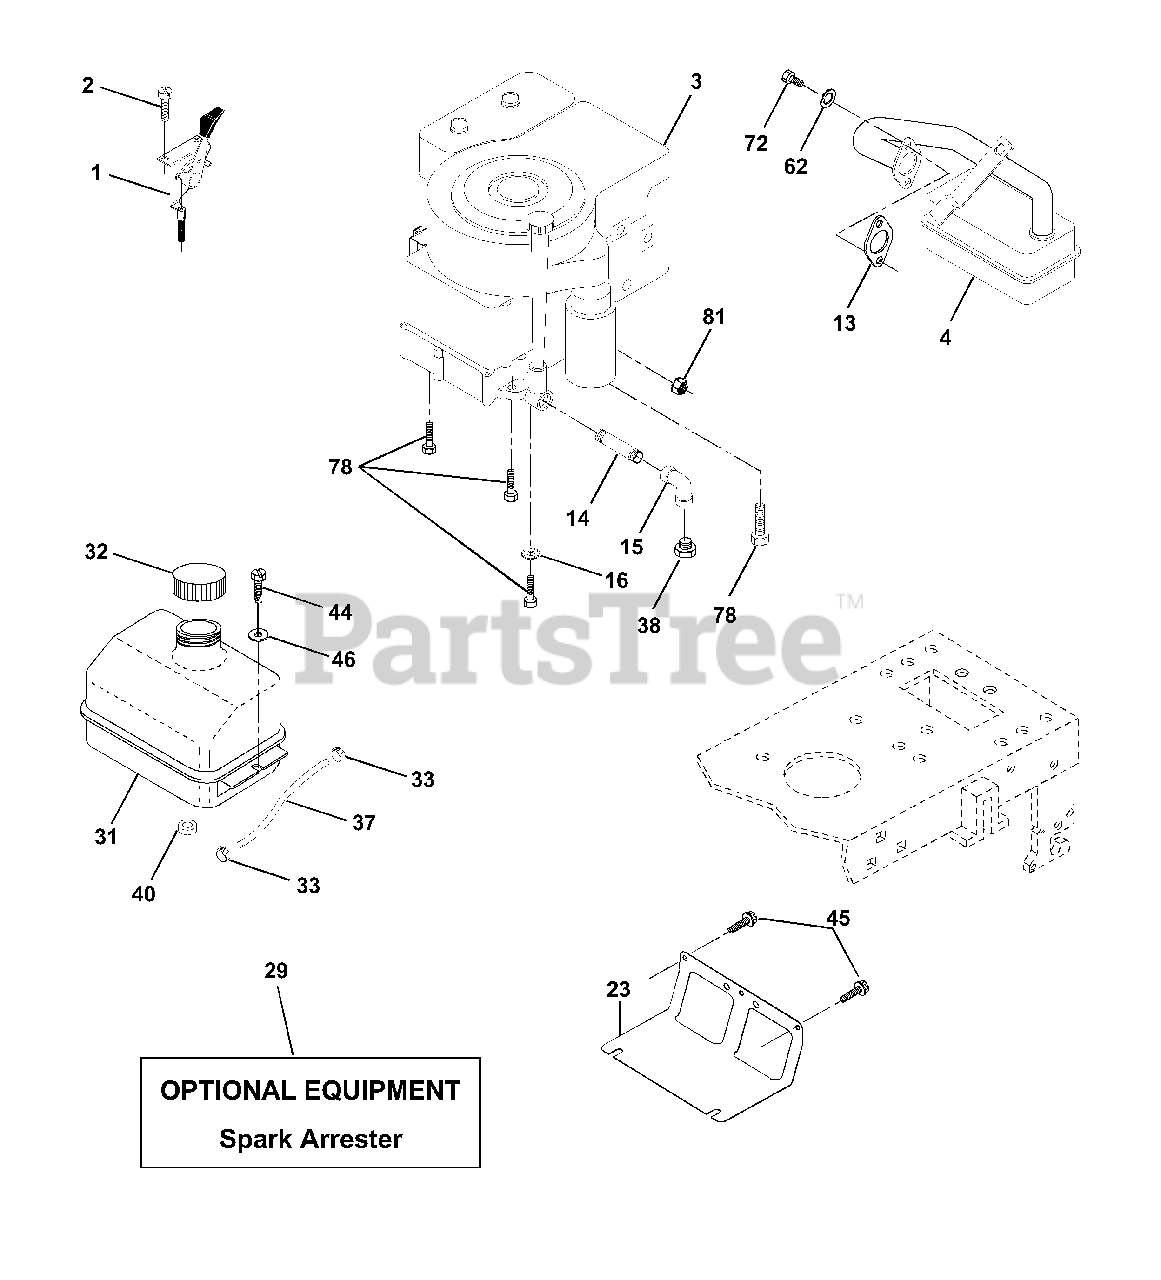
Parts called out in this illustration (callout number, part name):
1	Control Throt /Ch 23.5 Lh Flag
2	Screw Hex Thd Cut 1/4-20x5/8 T
4	Muffler Exhaust B&S Lt
13	Gasket 1 313 Id Tin Plated
14	Nipple Pipe 3/8 Npt X 3"
15	Elbow Std 90 Degree 3/8-18 Npt
16	Washer Lock Ext Tooth 3/8
23	Shield Browning/Debris Guard
29	Arrestor Spark
31	Tank Fuel 1 25 Fr
32	Cap Asm Fuel W/sym Vented
33	Clamp Hose Blk
37	Line Fuel 20"
38	Plug Oil Drain
40	Bushing Snap Nyl Blk Fuel Line
44	Screw Hexwsh Thdrol 1/4-20x3/4
45	Screw Hex Wsh Thdrol 3/8-16
46	Washer 9/32 X 7/8 X 16ga
62	Washer Lock Hvy Hlcl Spr 5/16
72	Screw Hexhd Cap 5/16-18x3/4
78	Screw Thdrol 3/8-16x1-1/4
81	Nut Keps Hex 1/4-20 Unc
